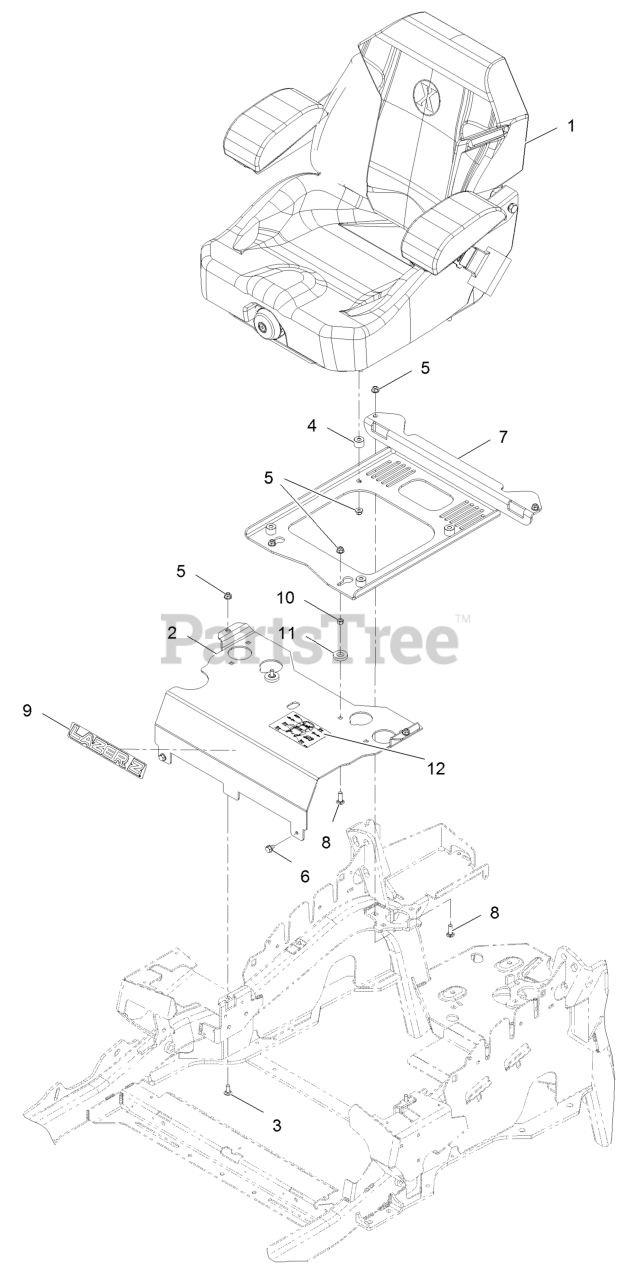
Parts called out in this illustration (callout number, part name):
1	KIT-SUSPENSION SEAT
2	Panel-Front, Seat Mount
3	SCREW-CARR
5	NUT-HF, NI
7	PLATE-SUPPORT, SEAT
8	SCREW-CARR
9	DECAL, LAZER MODEL
10	NUT-HEX
12	DECAL-SERVICE AID
